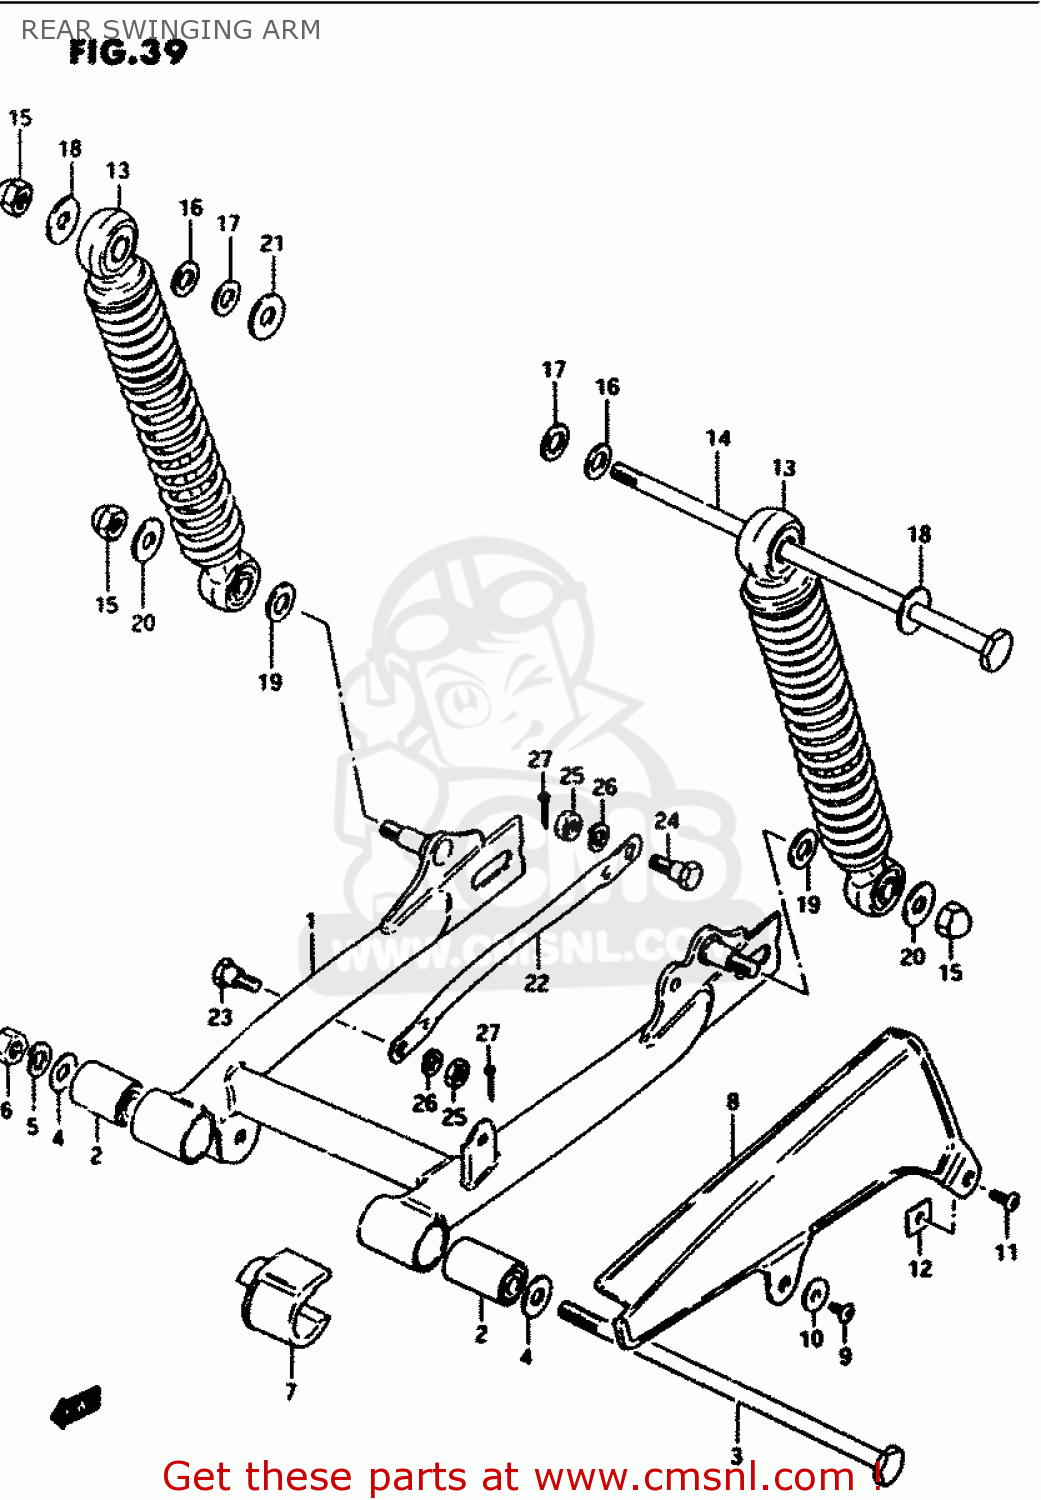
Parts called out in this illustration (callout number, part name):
1	SWINGING ARM, REAR (SILVER)
2	BUSH
3	SHAFT,REAR SWING ARM
4	WASHER
5	LOCK WASHER
6	NUT
7	BUFFER,CHAIN TOUCH DEFENSE
8	CASE, CHAIN (BLACK)
9	SCREW
10	WASHER
11	SCREW
12	NUT,CHAIN CASE RR
13	ABSORBER ASSY,RR SHOCK
14	SHAFT,RR SHOCK ABSORBER UPR
15	NUT
16	WASHER
17	WASHER(10.5X20X3.2)
18	WASHER
19	WASHER
20	WASHER
21	WASHER
22	TORQUELINK,RR
23	BOLT(8X22)
24	BOLT(8X26.5)
25	NUT
26	LOCK WASHER
27	PIN 20X20
